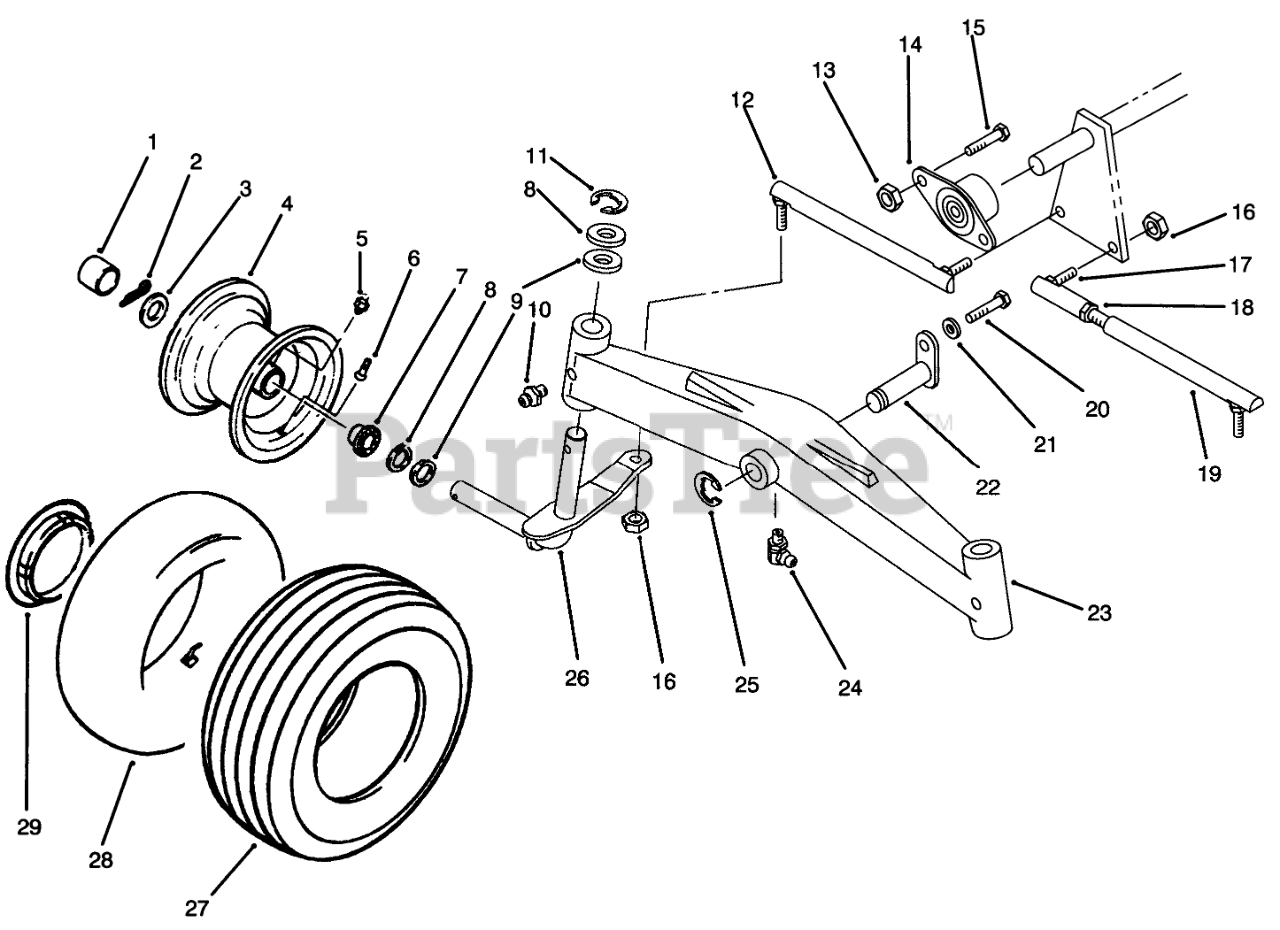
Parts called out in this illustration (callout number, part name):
1	HUBCAP
2	PIN-COTTER
3	WASHER WHEEL
4	Assembly-Wheel (Incl. Ref. #5-7)
5	ZERK-GREASE
6	VALVE
7	BEARING-WHEEL
8	WASHER
9	WASHER-SHIM
10	FITTING-GREASE
11	RING-RETAINING
12	Tie Rod RH
13	NUT-LOCK, NI
14	BEARING-FLANGED
15	SCREW-HH
16	NUT-LOCK
17	BALL-JOINT
18	NUT-HEX
19	Assembly-Tie Rod (Incl. Ref. #17 & 18)
20	SCREW-HH
21	WASHER-LOCK
22	PIN AND PLATE ASM
23	AXLE-FRONT
24	FITTING-GREASE
25	E-RING
26	RH SPINDLE WA
27	Tire (16 x 6.5-8) 2-Ply -2 Wheel Axel
29	8"-HUB CAP LOGO
